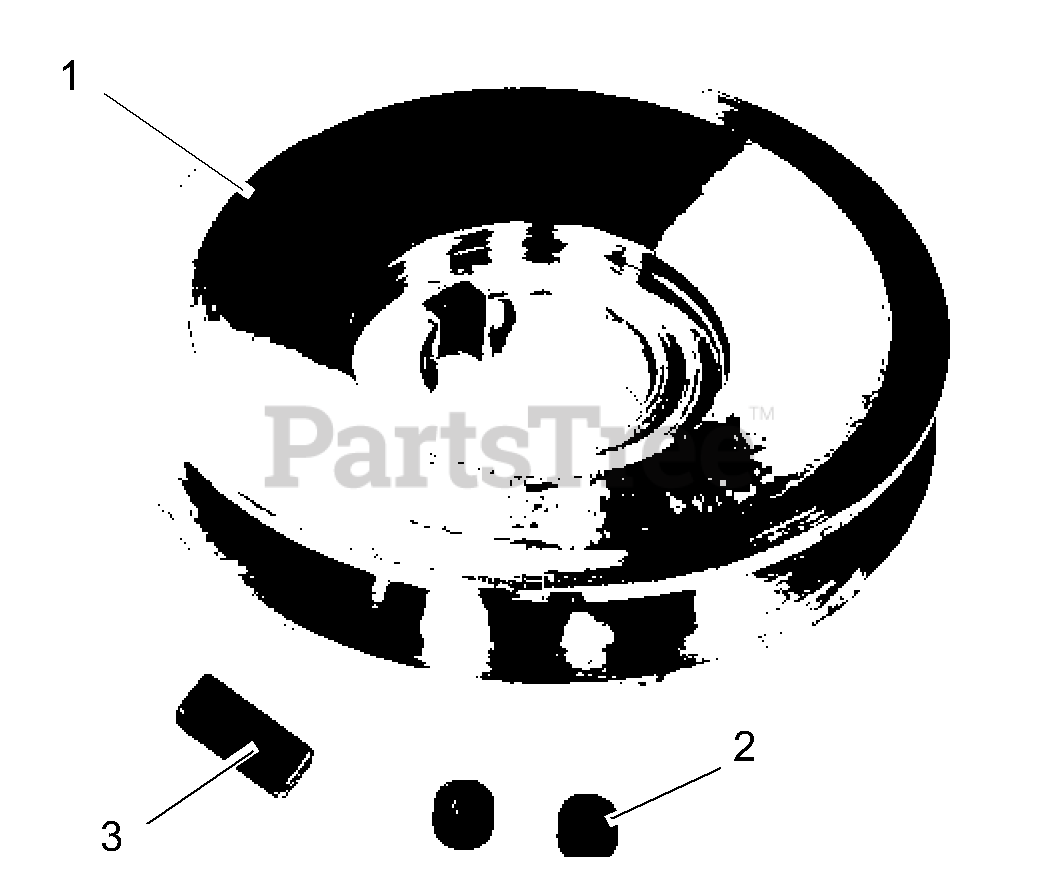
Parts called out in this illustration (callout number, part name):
1	Driven Pulley, 3-1/2" Diameter
2	Set Screw, 1/4-28 x 1/4
3	Square Key, 1/4 x 3/8 x 1/4
